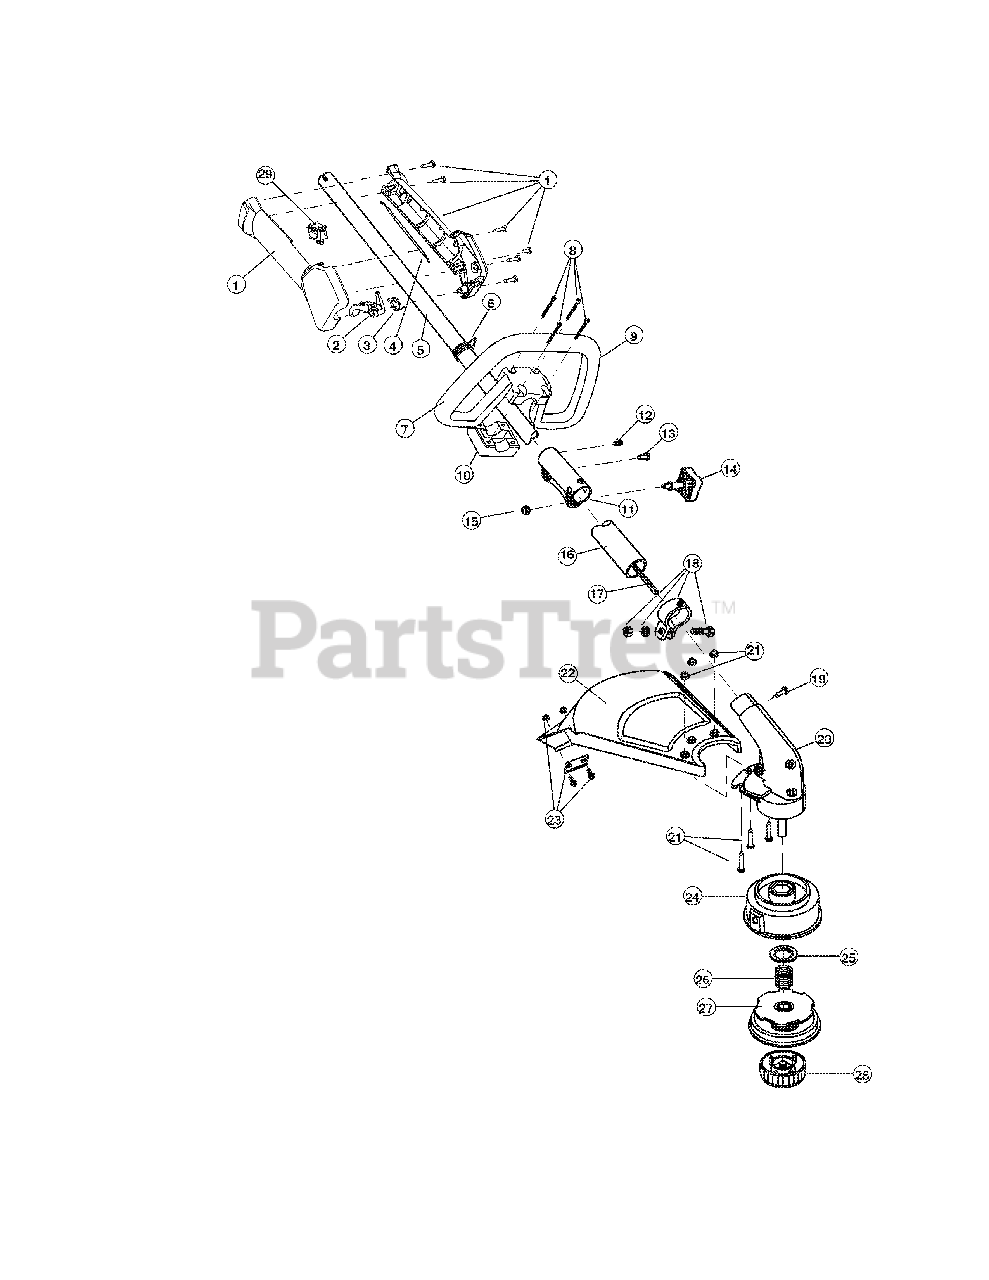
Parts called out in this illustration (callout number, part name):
1	Throttle Housing Assembly (includes 2 & 3)
2	Throttle Trigger
3	Throttle Trigger Spring
4	Throttle Cable Assembly
5	Upper Drive Shaft Housing Assembly
6	Harness Clip
7	Deluxe D-Handle Assembly (includes 8-10)
9	Deluxe D-Handle
10	Bottom Clamp
11	Split Boom Coupler (includes 12-15)
14	Adjustment Knob
15	Knob Retaining Nut
16	Lower Drive Shaft Housing Assembly
17	Lower Flexible Drive Shaft
18	Lower Clamp Assembly (includes 19)
19	Anti-Rotation Screw
20	Gear Box Assembly
21	Shield Mounting Hardware
22	Shield Assembly (includes 23)
23	Blade Assembly
24	Outer Spool Assembly (includes 25)
27	Inner Reel
28	Bump Head Knob Assembly
